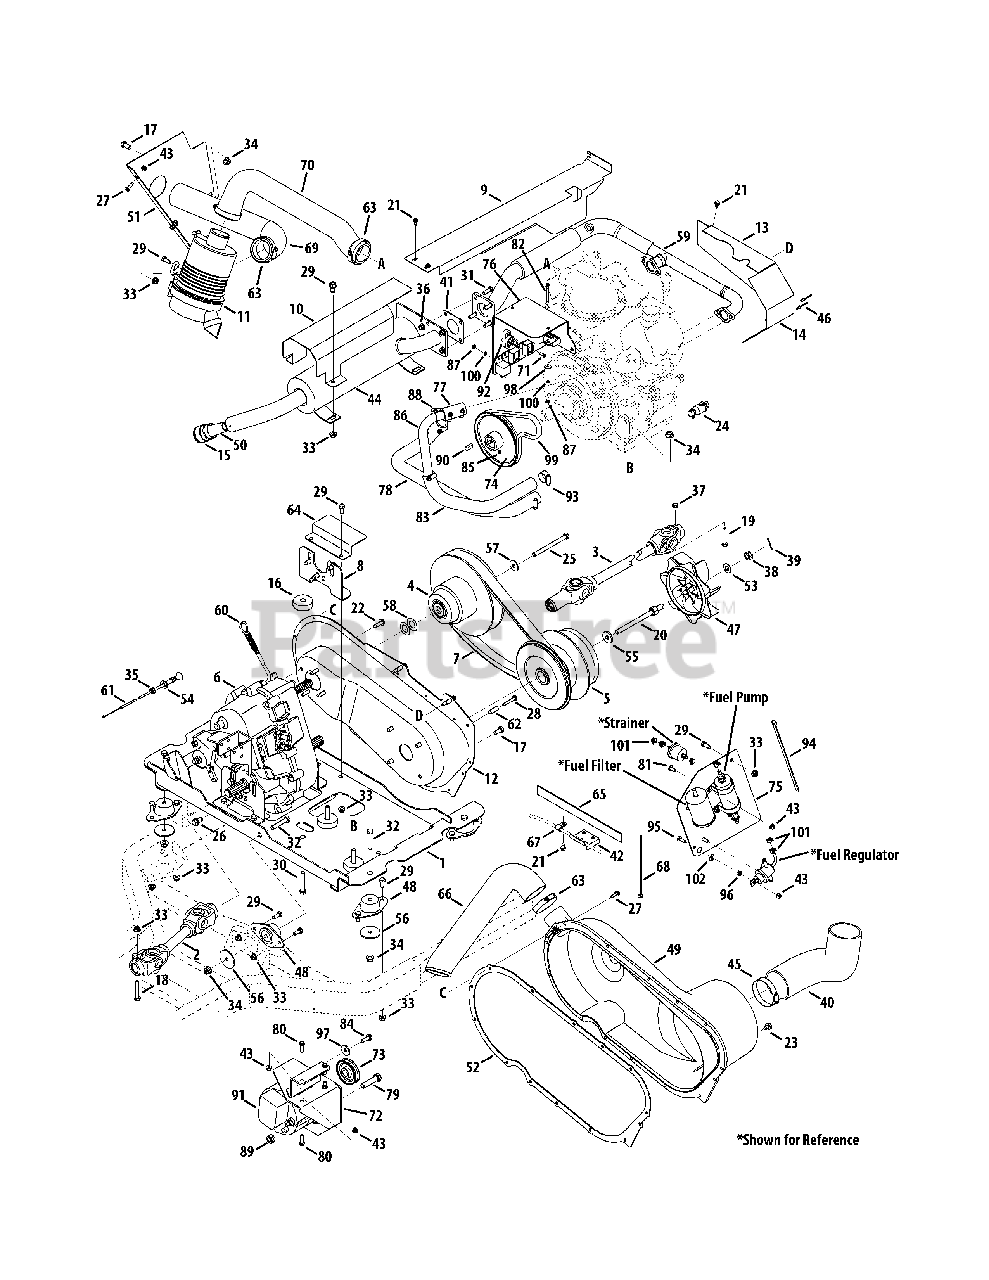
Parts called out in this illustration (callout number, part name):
1	Tray Assembly, Engine, Kohler
2	Shaft Assembly, Rr/prop
3	Shaft Assembly, Frt/prop, Hilliard
4	Clutch Assembly, Cvt, Driven
5	Clutch Assembly, Cvt, Driver, Cvr
6	Case Assembly, Transfer
7	Belt, Cvt, 4x4
8	Bracket, Trans, Mount
9	Cover, Heat, Shield
10	Exhaust, Shield, Heat
11	Filter Assembly, Air Cleaner
12	Cover, Back, Kohler
13	Cover, Eng, Kohler
14	Cover, Engine, Rr, Kohler"
16	Spacer, Engine, Kohl"
17	Hex Head Screw, 3/8-16, .75"
18	Hex Head Screw, 5/16-18, 2.00"
19	Hex Head Screw, 5/16-18, 1.875"
20	Hex Head Screw, 7/16-20, 5.00"
21	Screw, Tt, 1/4-20, 0.500"
22	Screw, Tt, 5/16-18, .875"
23	Screw, B, 5/16-12, 0.500"
24	Drain, Oil"
25	Hex Head Screw, 3/8-24, 2.25"
26	Screw, Tt, 3/8-16, 0.750"
27	Screw, Tt, 1/4-20, 0.750"
28	Screw, Tt, 1/4-20, 1.625"
29	Hex Head Screw, 5/16-18, .75"
30	Hex Head Screw, 3/8-16, 2.25"
31	Hex Head Screw, 5/16-18, .875"
32	Hex Head Screw, 3/8-16, 2.00"
33	Nut, Flange Lock, 5/16-18, Nylon"
34	Nut, Flange Lock, 3/8-16, Nylon"
35	Nut, Jam, 3/8-24"
36	Nut, Flange Lock, 5/16-18"
37	Nut, Hex Lock, 5/16-18, Ctrlk"
38	Nut, Hex, 1/2-20, Gr5, Slot"
39	Pin, Cotter, 3/32, 1.0"
40	Tube, Cvt, Intake"
41	Gasket, Engine"
42	Bracket, Cable Shield"
43	Nut, Flange Lock, 1/4-20"
45	Clamp, Hose, Adj."
46	Rivet, Pop, .125 Od, #42"
47	Impeller, Blower"
48	Compression Mount, Eng, Head"
49	Cover, Cvt"
50	Spark Arrester Screen
51	Plate, Baffle"
52	Seal, CVT, Cvr"
53	Washer, Flat, .510 x 1.00 x .060"
54	Washer, Flat, .406 x .875 x .059"
55	Washer, Flat, .450 x 1.250 x .164"
56	Washer, Flat, .38 x 2.00 x .12"
57	Washer, Bell, .396 x 1.140 x .095"
58	Washer, Flat, .793 x 1.368 x .025"
59	Pipe, Exhaust, Kohl, EFI"
60	Cable, Throttle Control, Kohler"
61	Cable, Choke Control, Kohler"
62	Spacer, .260 Id x .375od x 1.0l"
63	Clamp, Hose"
64	Shield, Harness"
65	Heat Shield Sleeve
66	Hose, CVT, Exhaust"
67	Clamp, Hose"
68	Tie, Cable"
69	Hose, Air, Inlet"
70	Hose, Air, Intake"
71	Screw
72	Support, Asm, Alternator, Kohler"
73	Pulley, 2.65 OD x 3L"
74	Pulley, 6.00 OD x 1.125"
75	Bracket, Fuel System, Kohler EFI"
76	Bracket, Electrical, Kohler EFI"
77	Hose, Rdtr, Top Rear"
78	Hose, Rdtr, Lower Rear"
79	Hex Head Screw, 1/2-13 x 2.00"
80	Screw, tt, 1/4-20 x 1.00"
81	Screw, Machine, 1/4-20 x .625"
82	Washer, Flat, .25 x .630 x .0515"
83	Hose, Radiator"
84	Screw, 5/16-18 x .875"
85	Screw, 1/4-20 x 3/8"
86	Tube, Rdtr"
87	Nut, Hex, #10-32"
88	Fitting, Petcock"
89	Nut, Hex Lock, 1/2-13"
90	Square key, 1/4 x .75lg"
91	Alternator, Aux, 65 Amp"
92	Electric Power Distribution Post
93	Clamp, Hose, Adj"
94	Tie, Cable"
95	Screw, Machine, 1/4-20 x .750"
96	Nut, Hex, 1/4-20"
97	Washer, Flat, .344 x 1.125 x .12"
98	Washer, Flat, .194 x .62 x .063"
99	Belt, V-Type"
100	Washer, Lock"
101	Clamp, Hose, .490 Dia."
